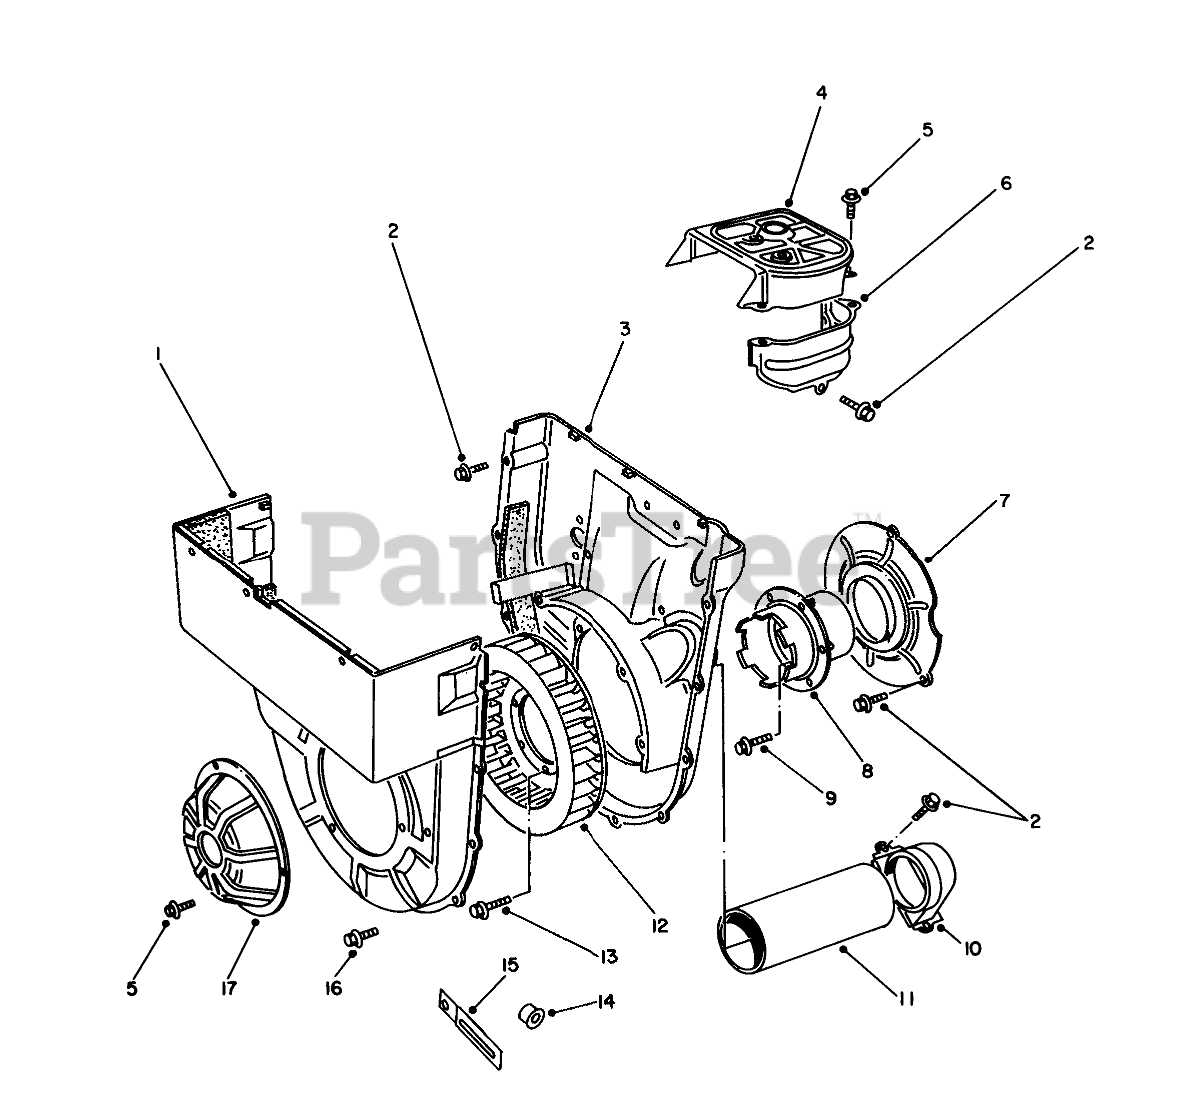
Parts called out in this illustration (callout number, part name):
1	Cover-Cooling Fan Outer
3	Cover-Cooling Fan Inner
4	Cowling-Upper
6	Cowling-Side
7	Cover-Magneto
8	Pulley
10	Guide-Air Duct
11	Tube-Air Duct
15	Clamp-Air Duct
16	SCREW-HHF
17	Cover
